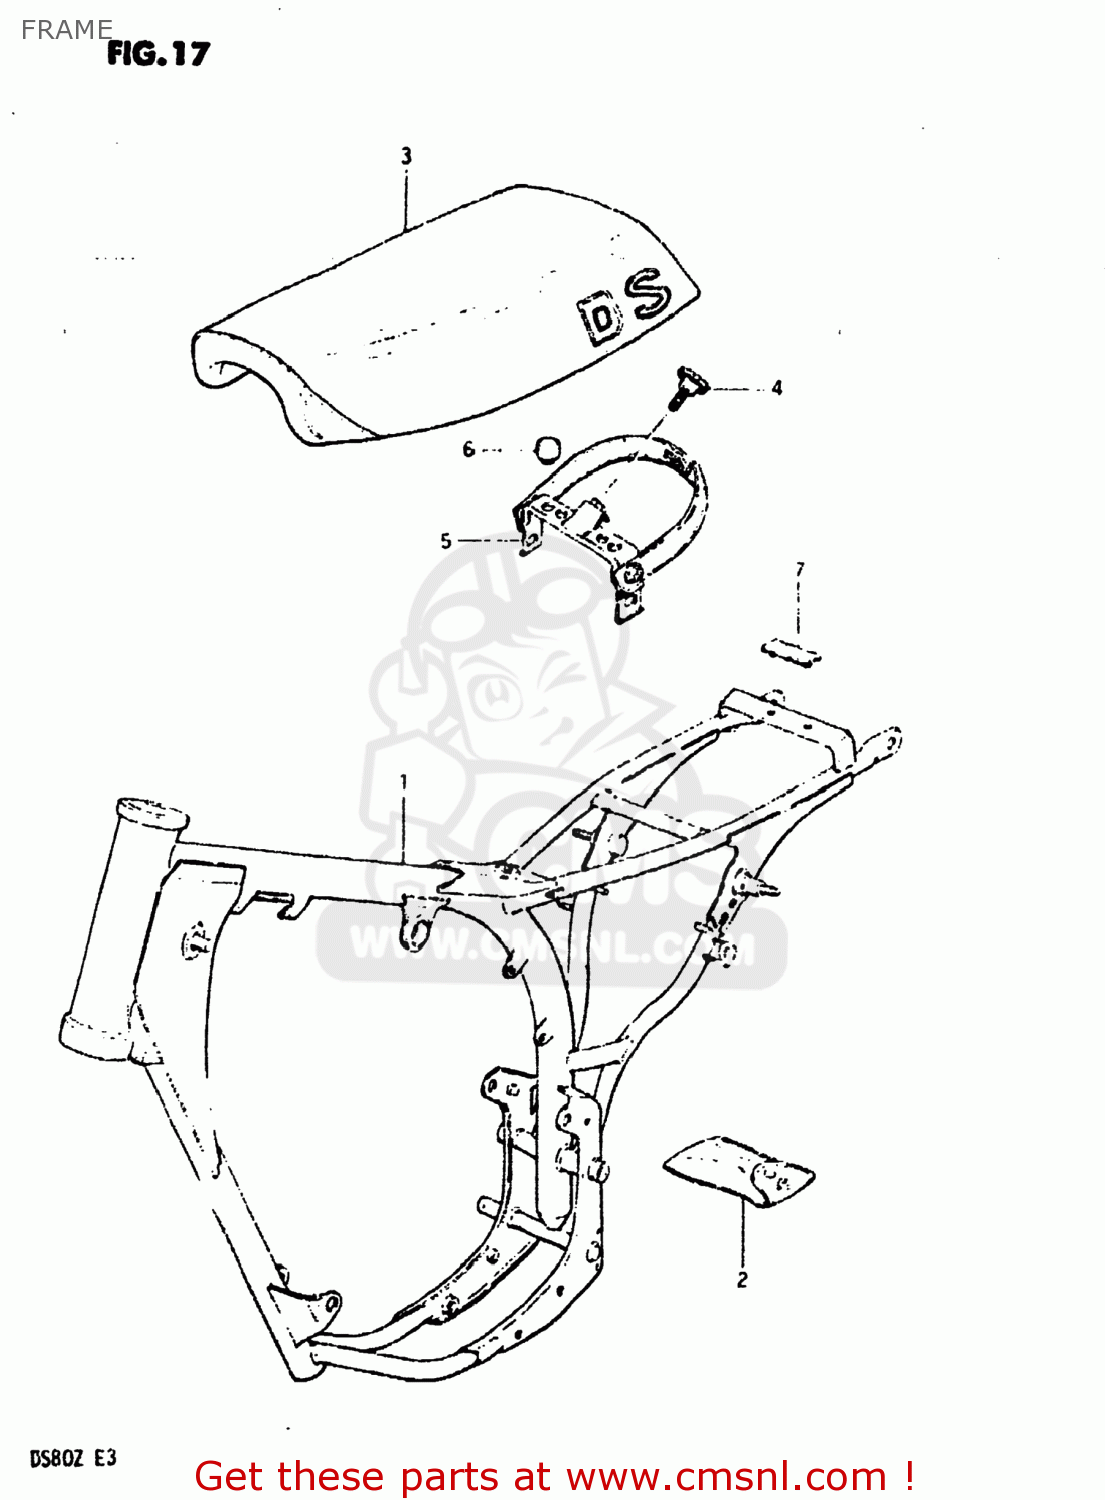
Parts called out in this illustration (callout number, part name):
1	FRAME
2	TOOL ASSY
3	SEAT ASSEMBLY
4	KNOB,FLAP SEAT TAIL
6	CUSHION(11.5X22X20)
7	CUSHION
